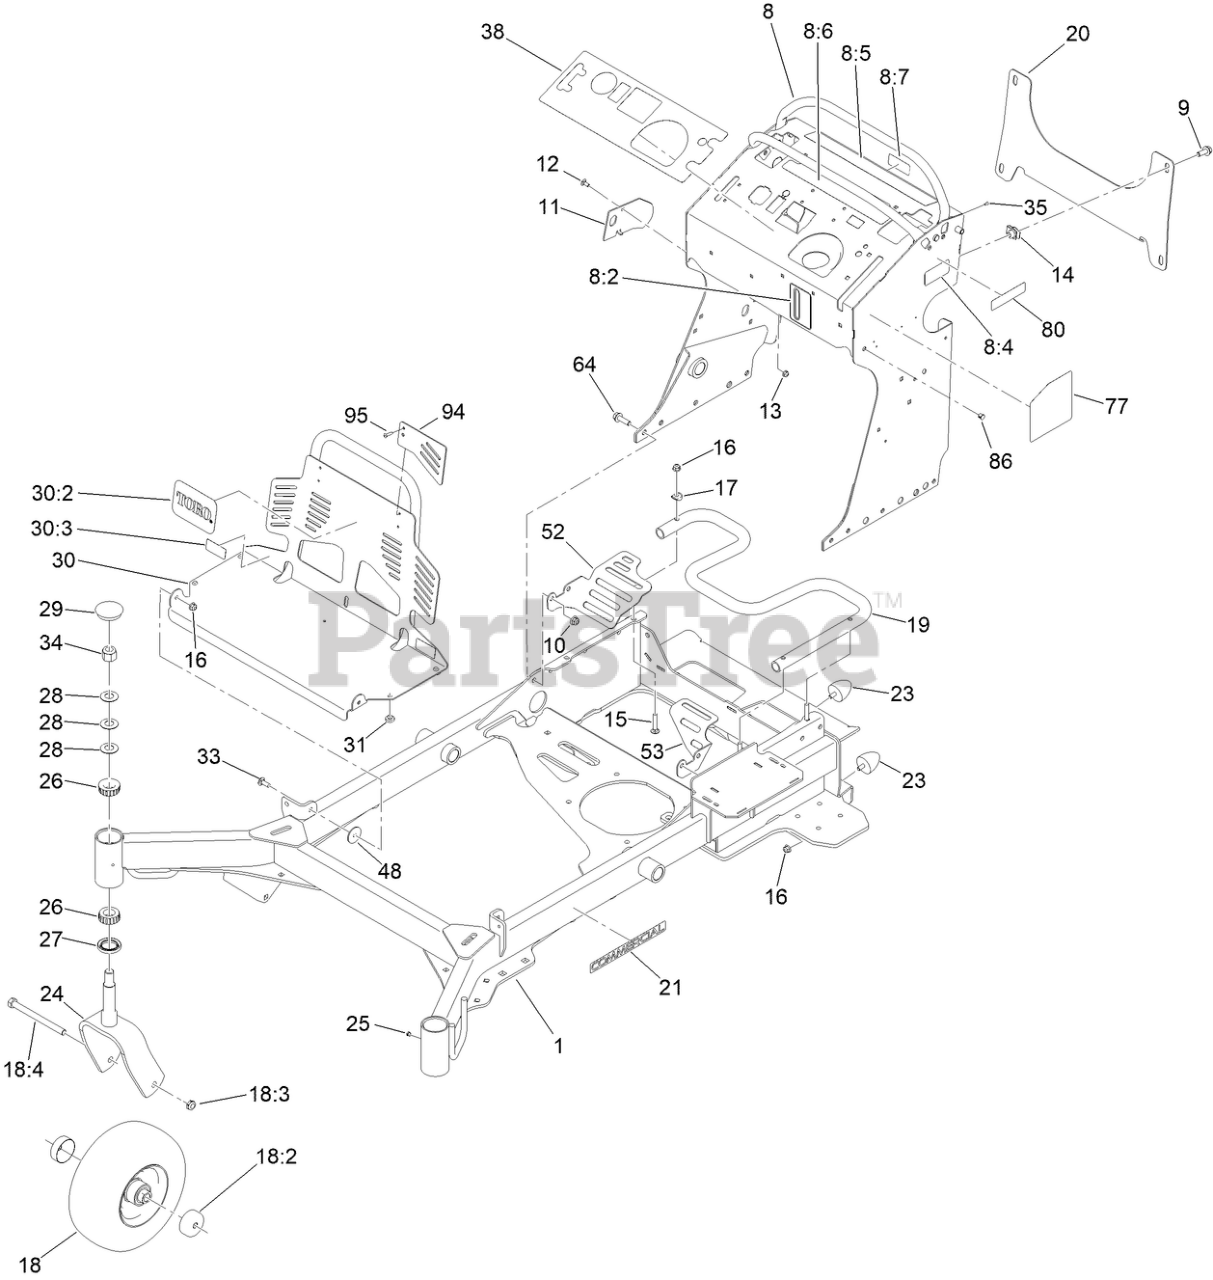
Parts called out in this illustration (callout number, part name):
1	FRAME-60 [RED]
8	TOWER DECAL ASM
8:2	DECAL-OIL LEVEL
8:4	DECAL-FILL, FUEL
8:5	DECAL-WARNING
8:6	DECAL-CONTROLS
8:7	DECAL - FUSE
9	SCREW-HHF
10	NUT-HF, NI
11	PLATE-STRIKER
12	SCREW-CARR
13	NUT-HF
14	NUT-TINNERMAN
15	BOLT-CAR
16	NUT-HF, NI
17	WASHER
18	MF WHEEL TIRE BEARING ASM
18:2	GUARD-SEAL
18:3	NUT-HEX
18:4	SCREW-HH
19	TUBE-MOUNT, FUEL TANK
20	BRACKET-CROSS
21	DECAL-COMMERCIAL
23	BUMPER-RUBBER
24	CASTER FORK ASM [RED]
26	BEARING-ROLLER, TAPERED
27	SEAL-GREASE
28	WASHER-BELLVILLE
29	CAP-GREASE
30	ENGINE GUARD ASM W/DECALS
30:3	DECAL-WARNING, NO RIDERS
31	BUMPER
33	BOLT-CARR
34	NUT-LOCK, NI
35	RIVET-POP
38	DECAL-PANEL, CONTROL
48	WASHER-NYLON
52	GUARD-FAN, RH
53	GUARD-FAN, LH
64	SCREW-HHF
77	DECAL-SERVICE AID
80	DECAL-ARRESTOR, SPARK
86	DOME PANEL PLUG
94	PLATE-GUARD
95	RIVET-TRIFOLD
